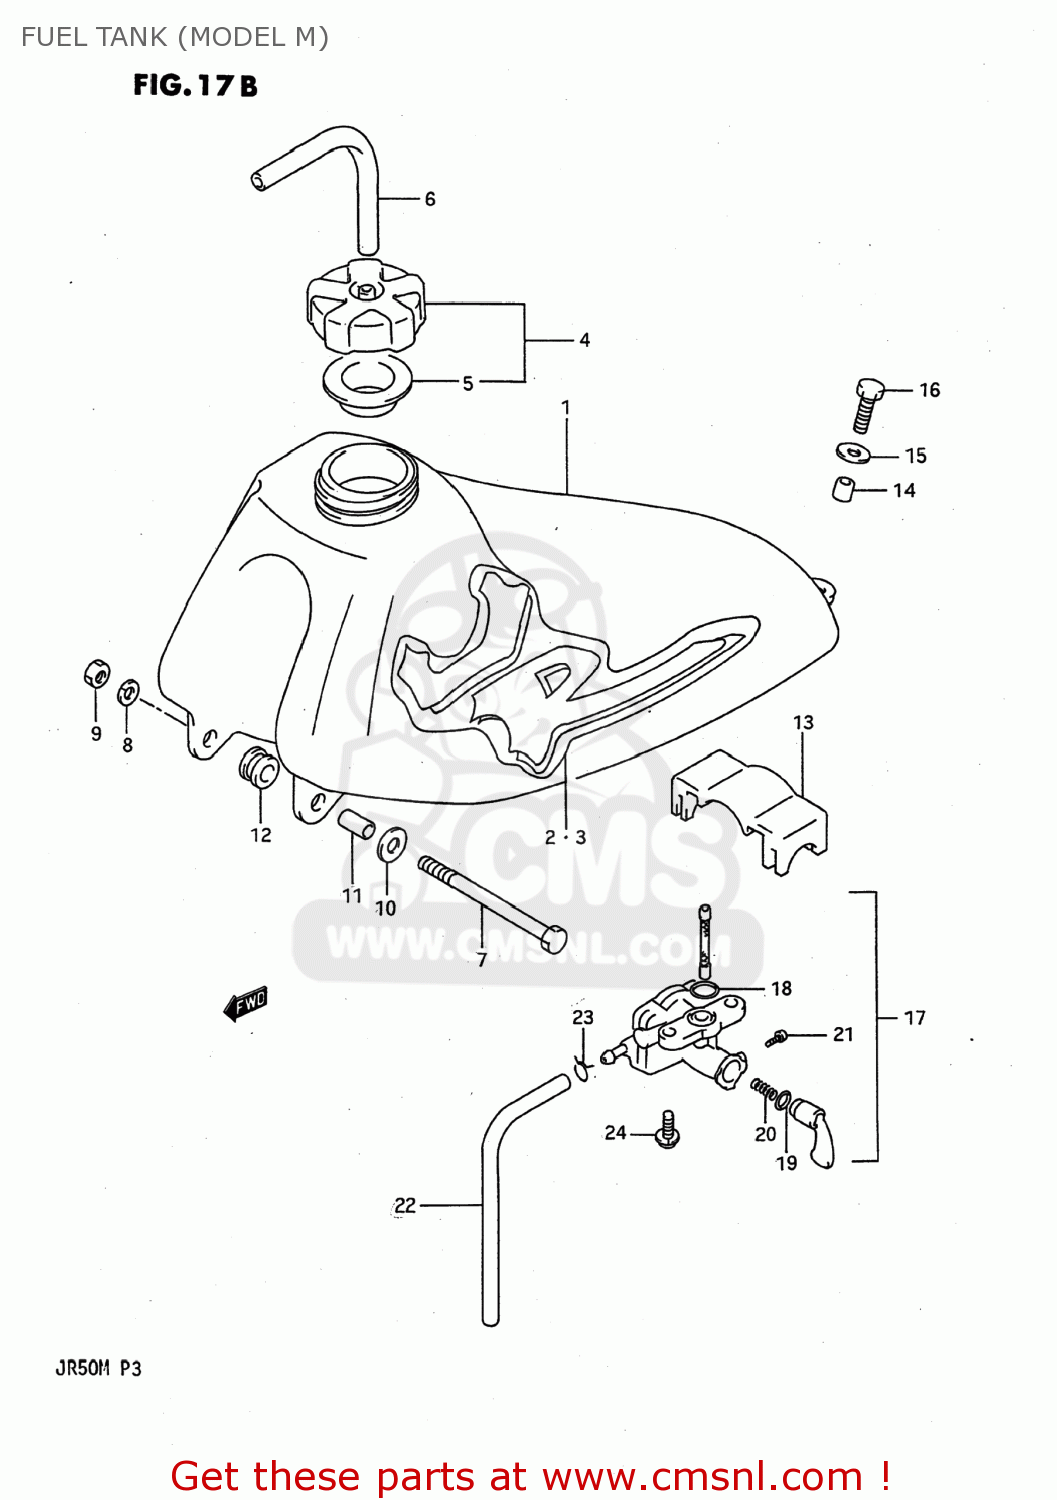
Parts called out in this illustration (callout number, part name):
1	TANK,FUEL
2	EMBLEM,FUEL TANK,RIGHT
3	EMBLEM,FUEL TANK,LEFT
4	CAP,FUEL TANK FILLER
5	GASKET,FUEL TANK CAP (NAS)
6	HOSE
7	BOLT
8	WASHER,LOCK
9	NUT 6MM
10	WASHER(6.5X18X1)
11	SPACER (6.8X10X11.5)
12	CUSHION
13	CUSHION,FUEL TANK UPR
14	SPACER
15	WASHER(6.5X18X1)
16	BOLT
17	COCK ASSY,FUEL
18	O RING
19	O RING,LEVER
20	SPRING,FUEL COCK VALUE
21	SCREW
22	HOSE
23	CLIP
24	SCREW
